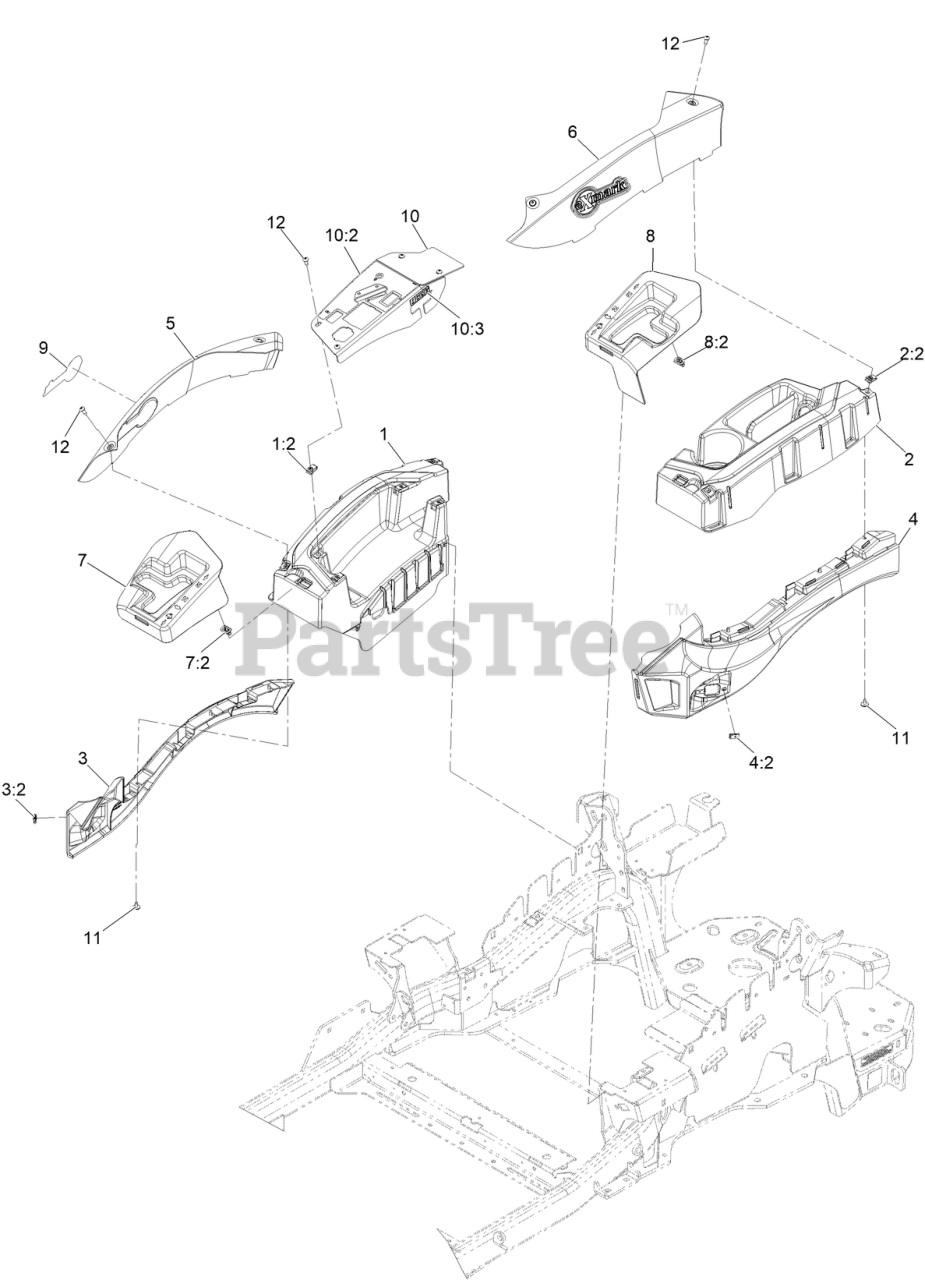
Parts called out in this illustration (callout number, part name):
1	CONSOLE-RH
2	CONSOLE-LH
3	ASM-Fender-RH
3:2	Nut-Speed
4	ASM-Fender-LH
4:2	Nut-Speed
5	PANEL-SIDEPOD ACCENT
6	Panel-Sidepod Accent [red]
7	ASM-MOTION CONTROL COVER RH
7:2	Clip-Trim
8	ASM-MOTION CONTROL COVER LH
8:2	Clip-Trim
9	DECAL-EXMARK LOGO
10	ASM-Console Panel W/Decals
10:2	DECAL-CONTROL PANEL EFI
10:3	DECAL-FUSES
11	SCREW-TORX
12	SCREW-TPH THD FORM
